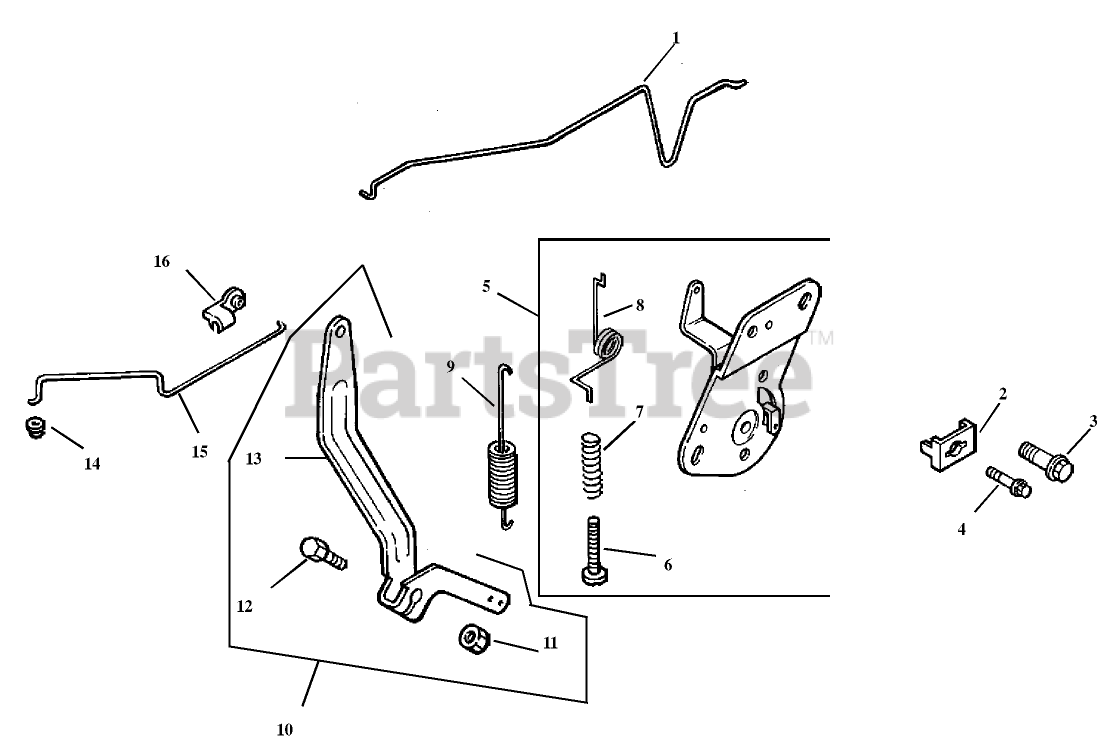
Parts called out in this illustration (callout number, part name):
1	Linkage-Choke
2	CLAMP-CABLE
3	Screw-Socket, 6 Lobed (Thread Forming, M6x1.0x20)
4	SCREW-FLANGE, THREAD FORMING (M5X0.8X16)
5	Control-Speed ASM (Incl. 6-8)
6	Screw-SPH,M4x0.7x25
7	Spring-Control, Speed
8	Spring-Return, Choke
9	Spring-Governor
10	Kit-Governor Lever (Incl. 11-13)
11	Nut-Flange, Hex (1/4-20)
12	Bolt-Square Neck, Round Head (1/4-20x1)
13	Lever-Governor
14	BUSHING-LINKAGE, THROTTLE
15	Linkage-Throttle
16	BUSHING-RETAINING, LINKAGE
